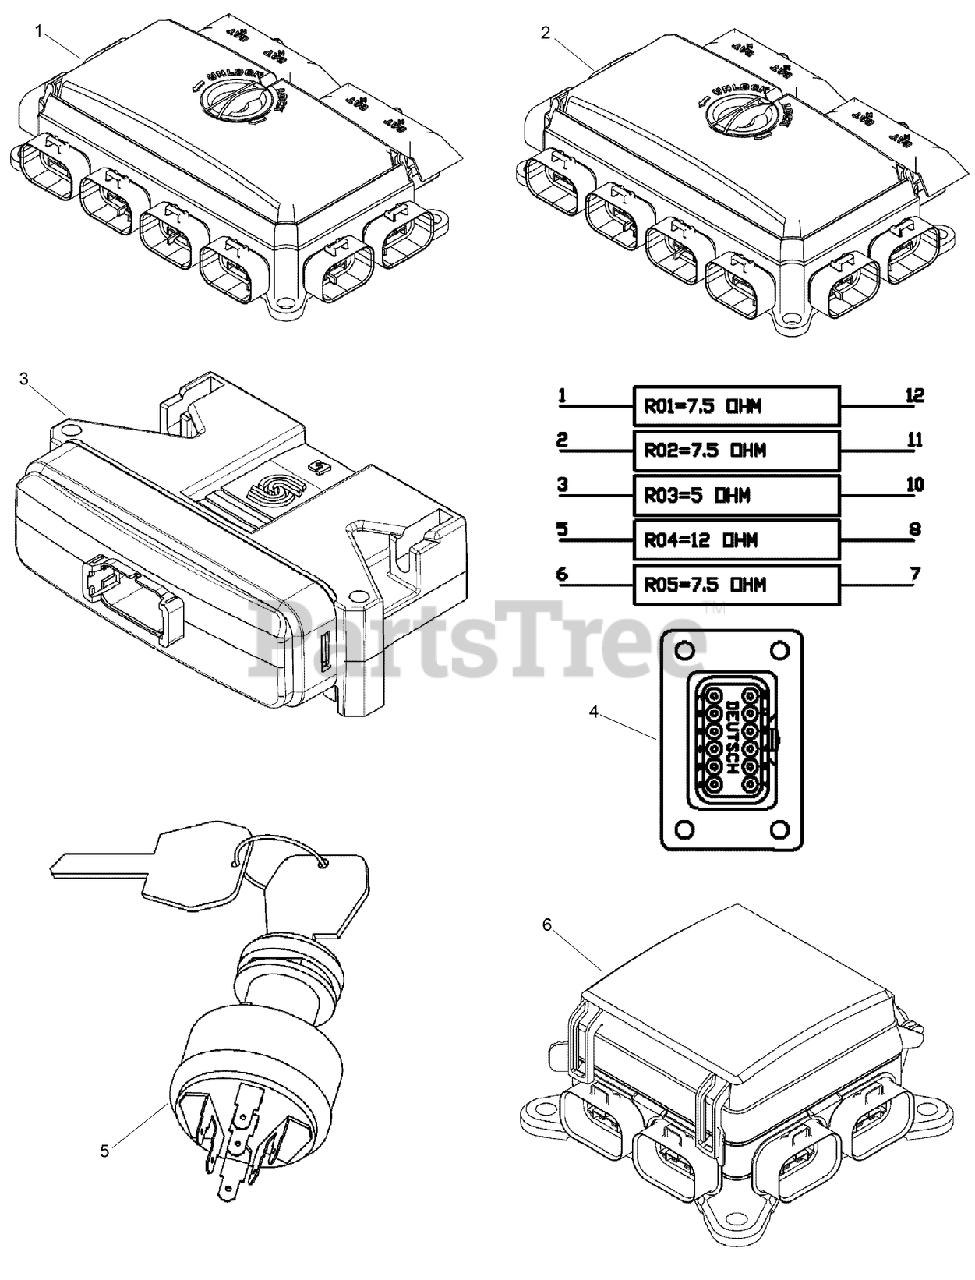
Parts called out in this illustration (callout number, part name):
1	BOX-VEC, MAIN (A)
2	BOX-VEC, MAIN (B)
3	COMPUTER-EXPANDER, OUTPUT
4	CONNECTOR-PACK, RESISTOR
5	ASSEMBLY - Ignition Switch
6	BOX-VEC, MAIN (C)
